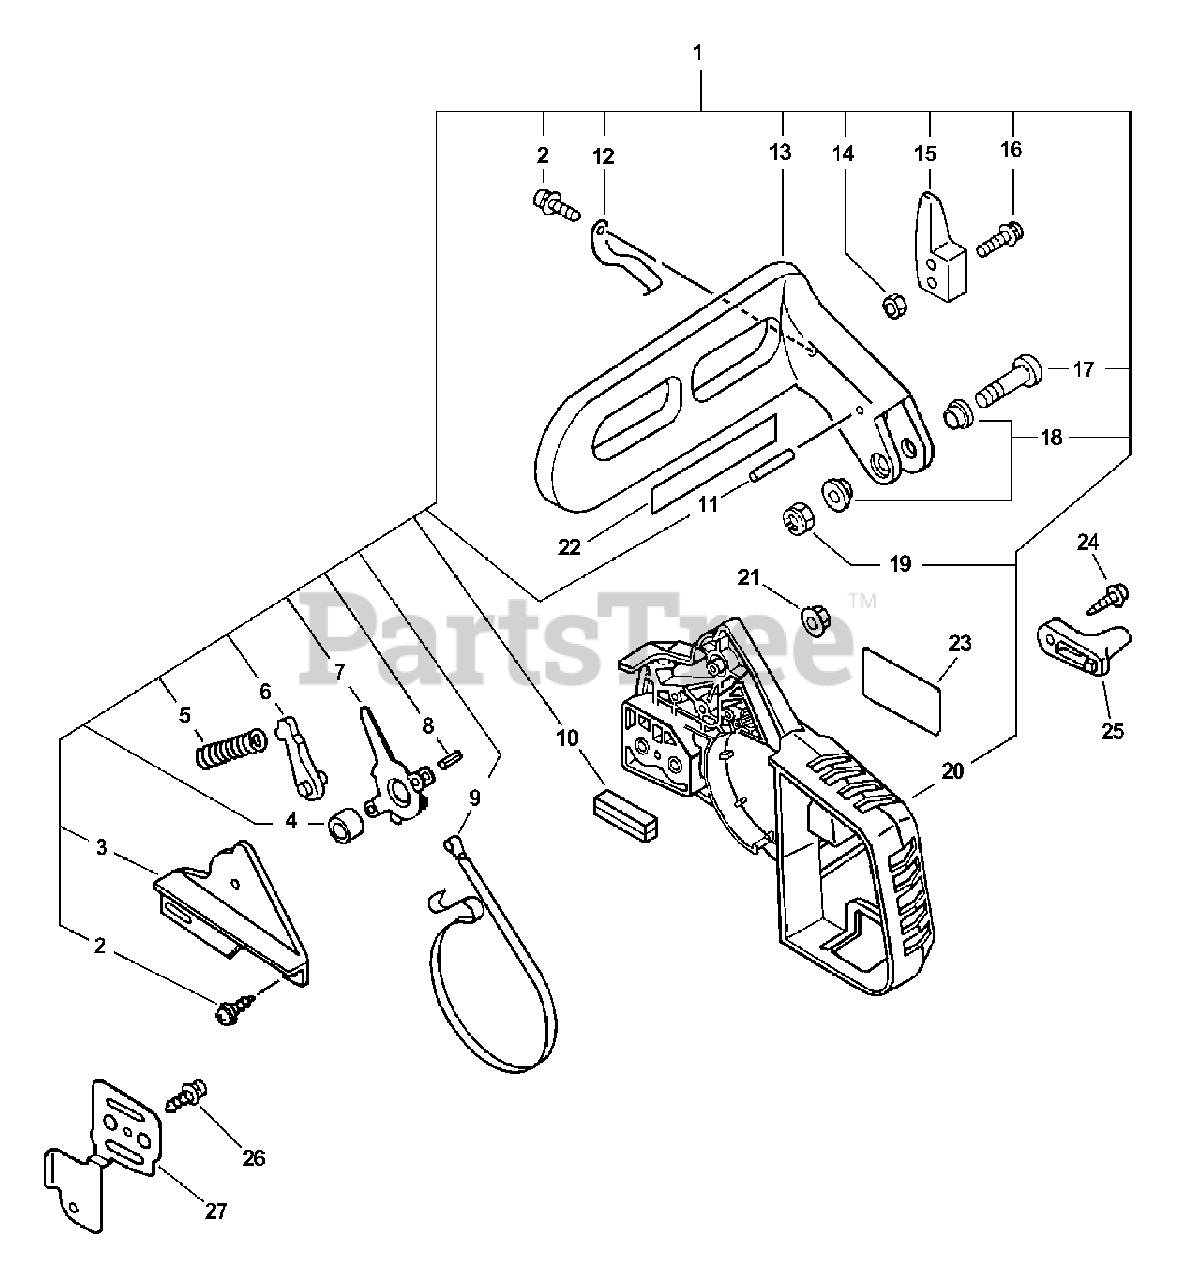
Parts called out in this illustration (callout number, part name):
1	CHAIN BRAKE ASSY
2	SCREW 4×10
3	COVER, BRAKE
4	SPACER 8×12×9
5	SPRING, COMPRESSION
6	STOPPER, BRAKE
7	LEVER, BRAKE
8	PIN, SPRING 4×8.8
9	BAND, BRAKE
10	SEAL, BRAKE
11	ROLLER 4×23.8
12	SPRING, FLAT
13	LEVER, BRAKE
14	NUT M4
15	WEIGHT, BRAKE
16	SCREW 4×20
17	SCREW 5×30
18	COLLAR 5.3×10×13×L5
19	NUT, LOCK M5
20	GUARD, SPROCKET
21	NUT, FLANGE M6
22	LABEL, BAR & CHAIN
23	LABEL, CS-3450
24	SCREW, TAPPING 5×20
25	CHAIN CATCHER
26	SCREW 4×10
27	PLATE, GUIDE
